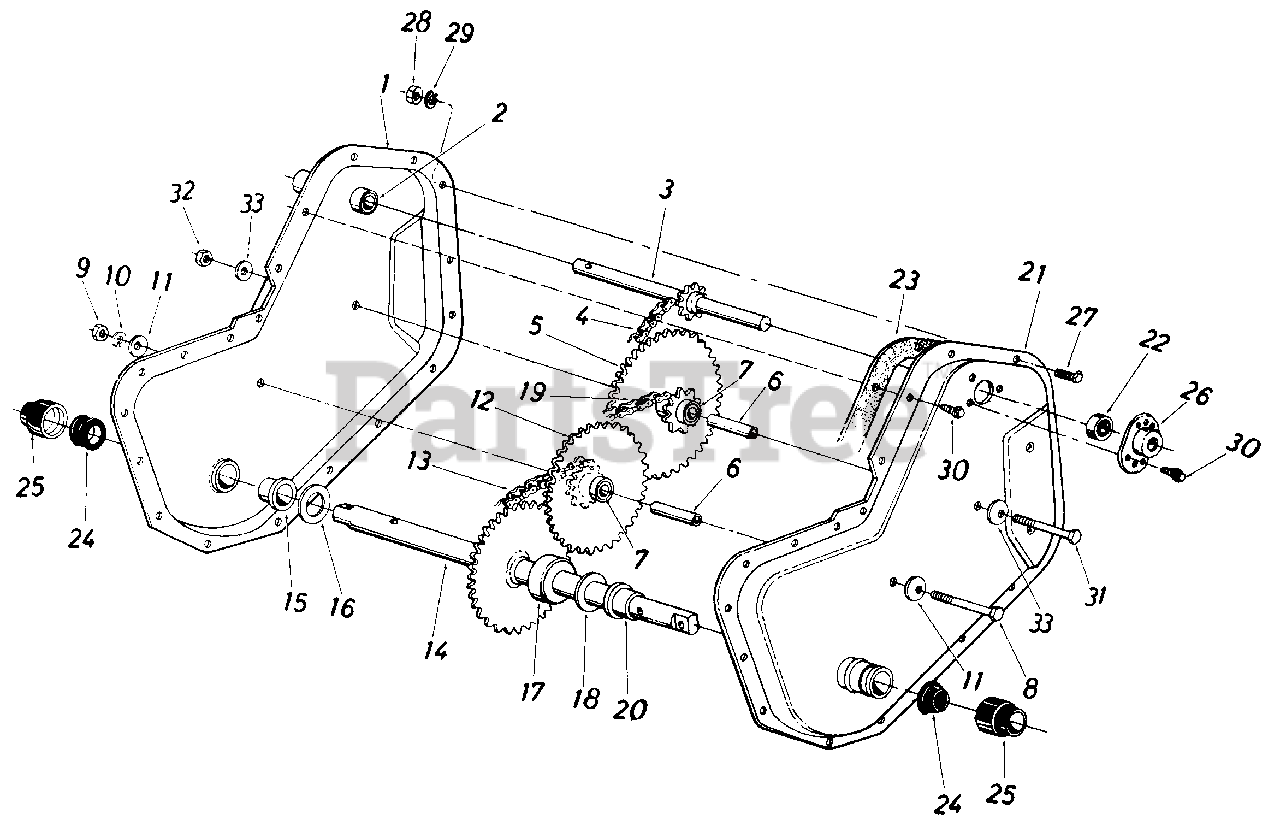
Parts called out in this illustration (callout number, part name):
1	Chain Case Half Ass'y.-R.H.
2	Bearing 5/8" I.D. x .813" O.D. x 1.31" Lg.
3	Input Shaft Ass'y.
4	Chain #35-3/8" Pitch x 44 Links
5	Sprocket and Hub Ass'y.
6	Bearing Inner Axle
7	Sleeve Brg. 5/8" I.D. x 3/4" O.D. x 1.50
8	Hex Bolt 3/8-24 x 2.50" Lg.
9	Hex Ins. L-Nut 3/8-24 Thd.
10	L-Wash. 3/8" I.D.*
11	Bell-Wash. .41" I.D. x 1.13" O.D. x .03
12	Sprocket & Hub Ass'y. 9T-22T
13	#420 Chain 1/2 Pitch x 28 Links Endless
14	Wheel Shaft Ass'y.
15	Flange Bearing
16	Fl-Wash. .88" I.D. x 1.5"* O.D. x .03
17	Spacer 7/8" I.D. x 13/4" O.D. x.68" Lg.
18	Fl-Wash. .88" I.D. x 1.50" O.D. x .03
19	#420 Chain 1/2" Pitch x 30 Links Endless
20	Flange Bearing
23	Gasket
26	Bearing Housing
27	Hex Bolt 1/4-28 x 5/8" Lg.
28	Hex Nut 1/4-28 Thd.
29	L-Wash. 1/4" I.D.*
30	Hex Wash. S-Tap Scr. 1/4-20 x.50" Lg.
31	Hex Bolt 5/16-18 x 2.5" Lg.
32	Hex Cent. L-Nut 5/16-18 Thd.
33	Fl-Wash. 5/16" I.D.
